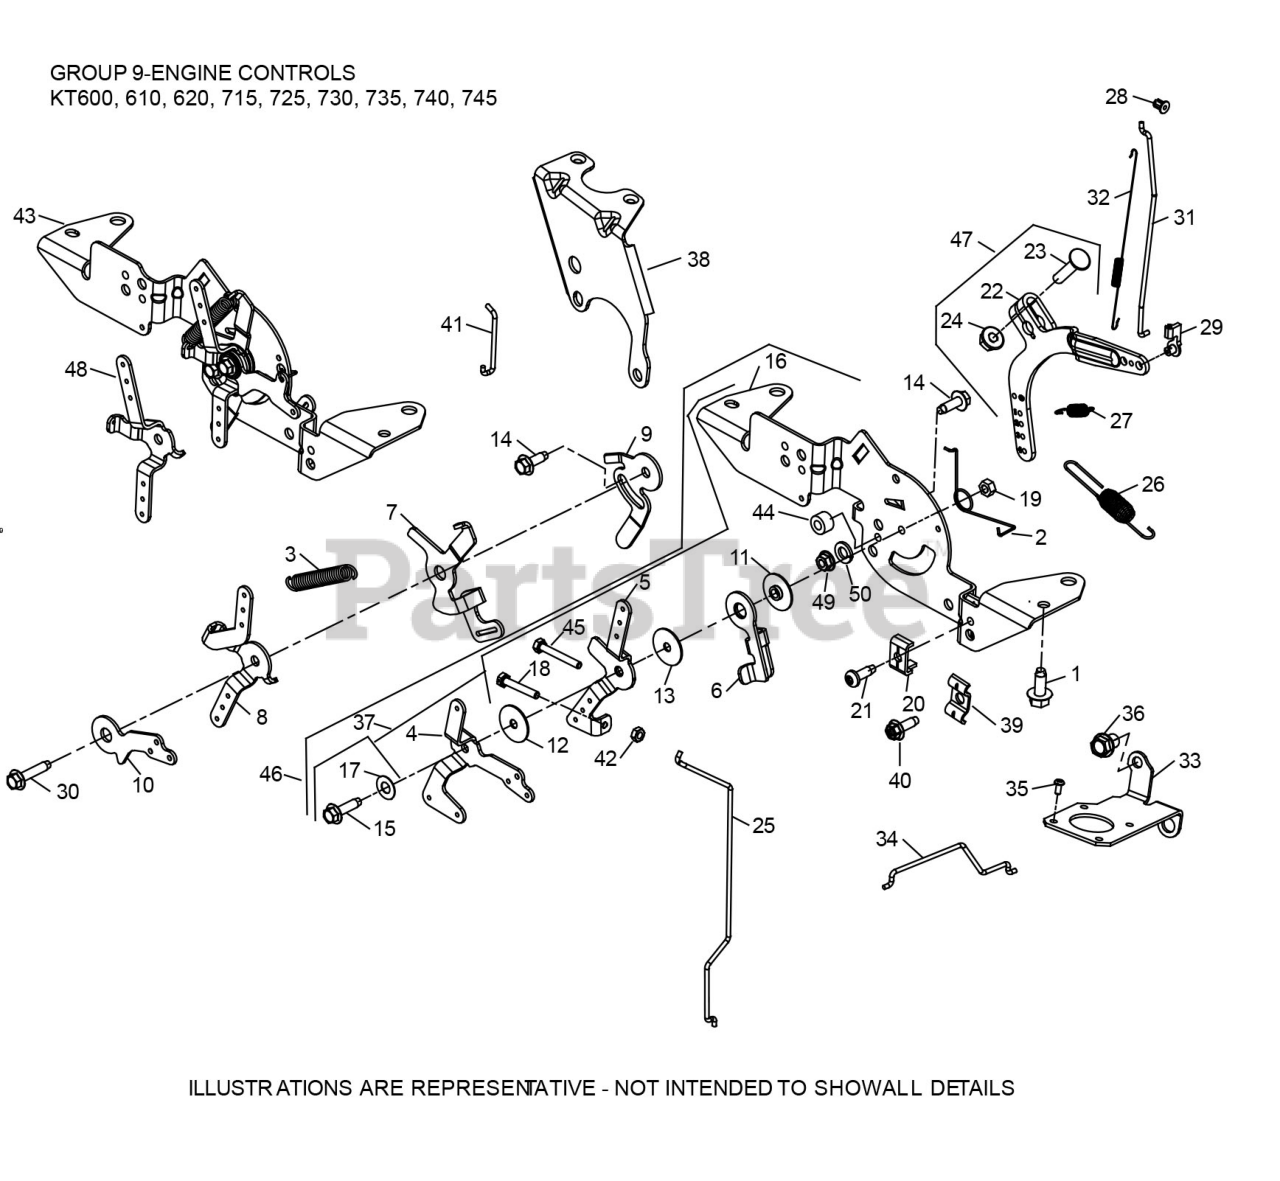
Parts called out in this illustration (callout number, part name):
1	SCREW-THREAD FORMI
2	SPRING-CHOKE RETRN
5	LEVER-THROTTLE CON
6	LEVER-THROTTLE ACT
11	SPACER-CONTROL ASSEMBLY
15	THREAD FORMING SCREW
16	SPEED CONTROL BRACKET
22	LEVER-GOVERNOR ASSEMBLY
23	BOLT-RD HD SQ NECK
24	HEX FLANGE NUT
25	CHOKE LINKAGE
26	GOVERNOR SPRING
27	GOVERNOR SPRING
29	BUSHING-RETAINING
32	LINKAGE SPRING
34	THROTTLE LINKAGE
40	THREAD FORMING SCREW
46	SPEED CONTROL ASSEMBLY
47	LEVER-GOVERNOR ASSEMBLY
